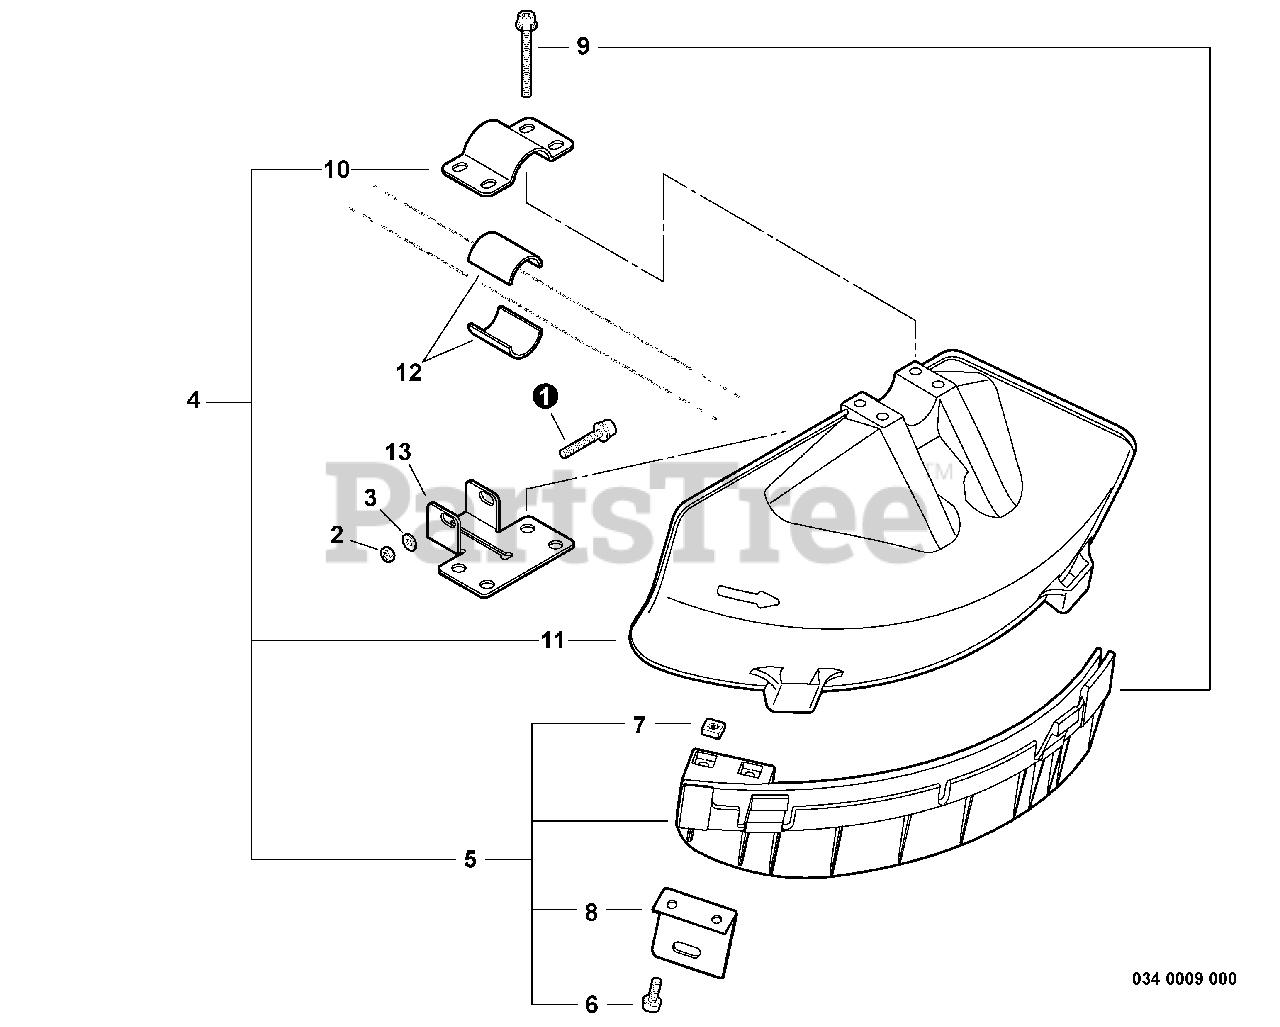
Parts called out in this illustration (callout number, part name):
1	SCREW - 6X40
2	LOCKNUT - 6
3	WASHER - 6
4	DEBRIS SHIELD KIT - PLASTIC
5	SHIELD GUARD KIT
6	SCREW - 5X16
7	NUT - 5
8	KNIFE, TRIMMER LINE
9	SCREW - 5X45
10	CLAMP - UPPER
11	SHIELD, DEBRIS
13	BRACKET, SHIELD
